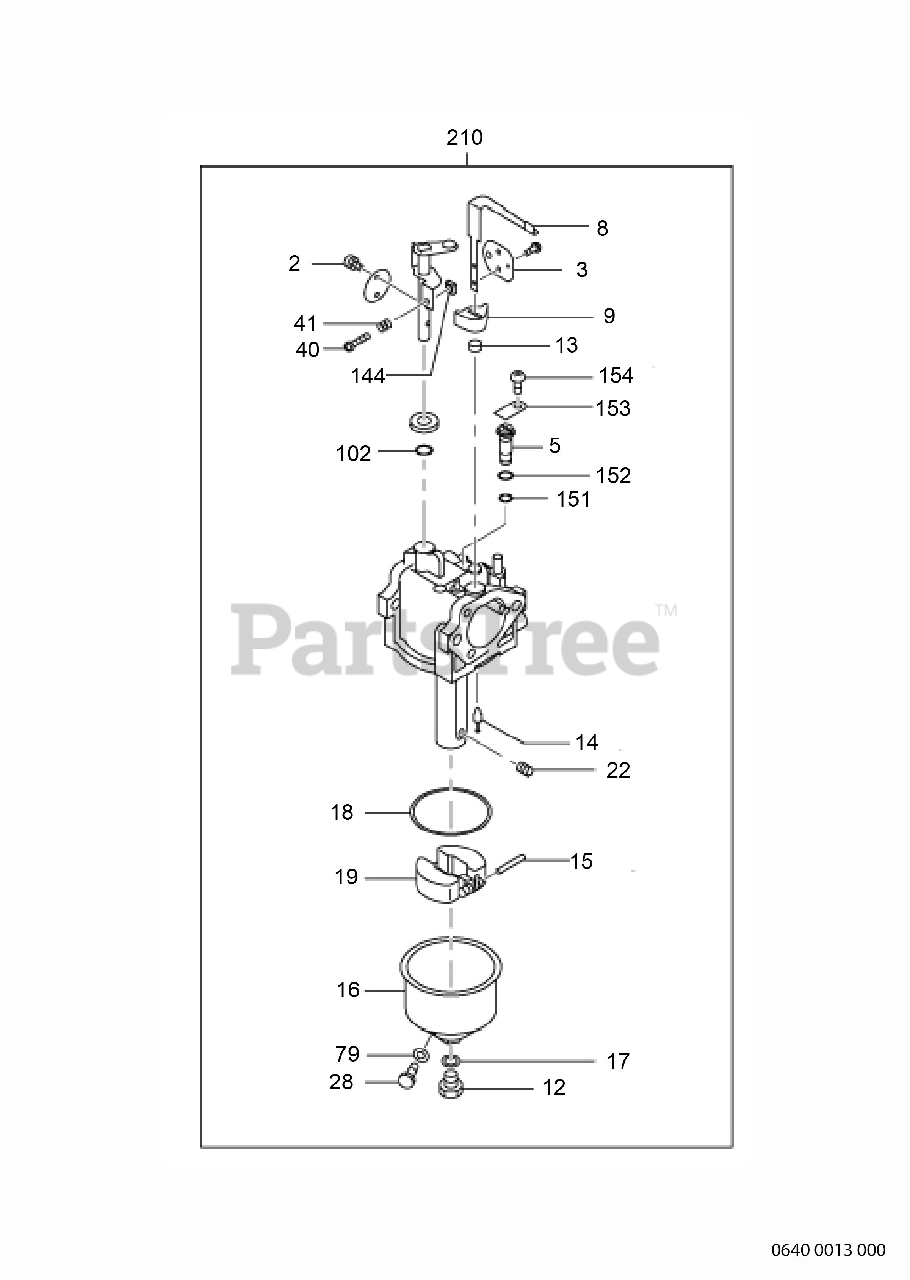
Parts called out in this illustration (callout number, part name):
3	CHOKE VALVE
5	SLOW JET
8	CHOKE LEVER
9	SHAFT COLLAR 1
12	SET SCREW
13	SHAFT COLLAR 2
14	NEEDLE VALVE ASSY
15	PIN, FLOAT LEVER
16	FLOAT CHAMBER SUB AY
18	GASKET, CHAMBER
19	FLOAT SUB ASSY
22	MAIN JET
40	SCREW, ADJUSTING
79	GASKET
144	NUT
153	PLATE
210	CARBURETOR AY
